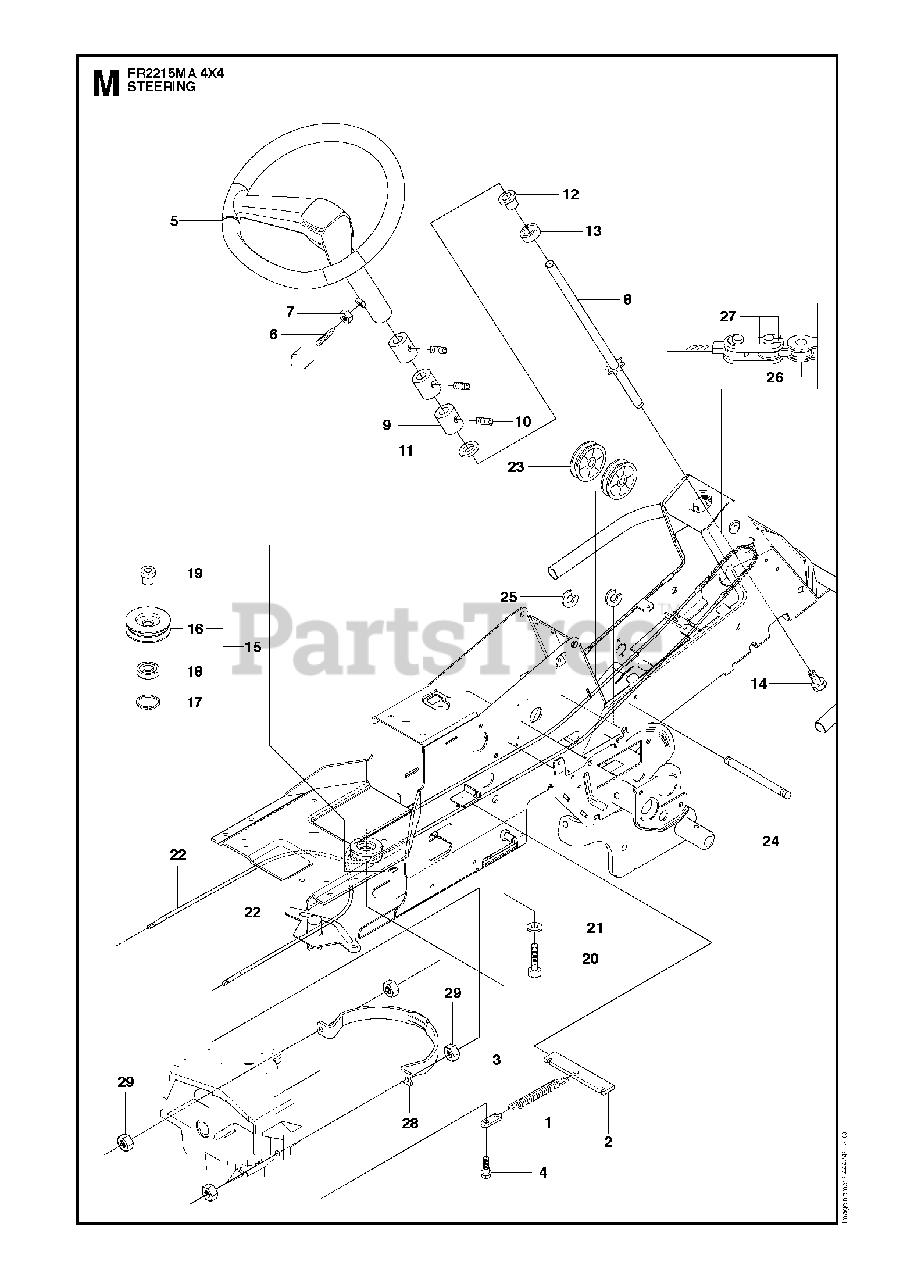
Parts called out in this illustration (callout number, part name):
2	SPRING BRACKET
3	CONNECTOR
5	STEERING WHEEL
7	NUT
8	ROD STEERING ASSY
13	BALL BEARING 6004-2RS1
16	ROLLER
17	CIRCLIP SGH 47
18	BALL-BEARING 6204-2RS
19	BUSHING
20	COLLAR SCREW
22	RP STEERING CABLE COMPLETE
25	RETAINING RING
26	STEERING CHAIN
28	WIRE GUIDE
